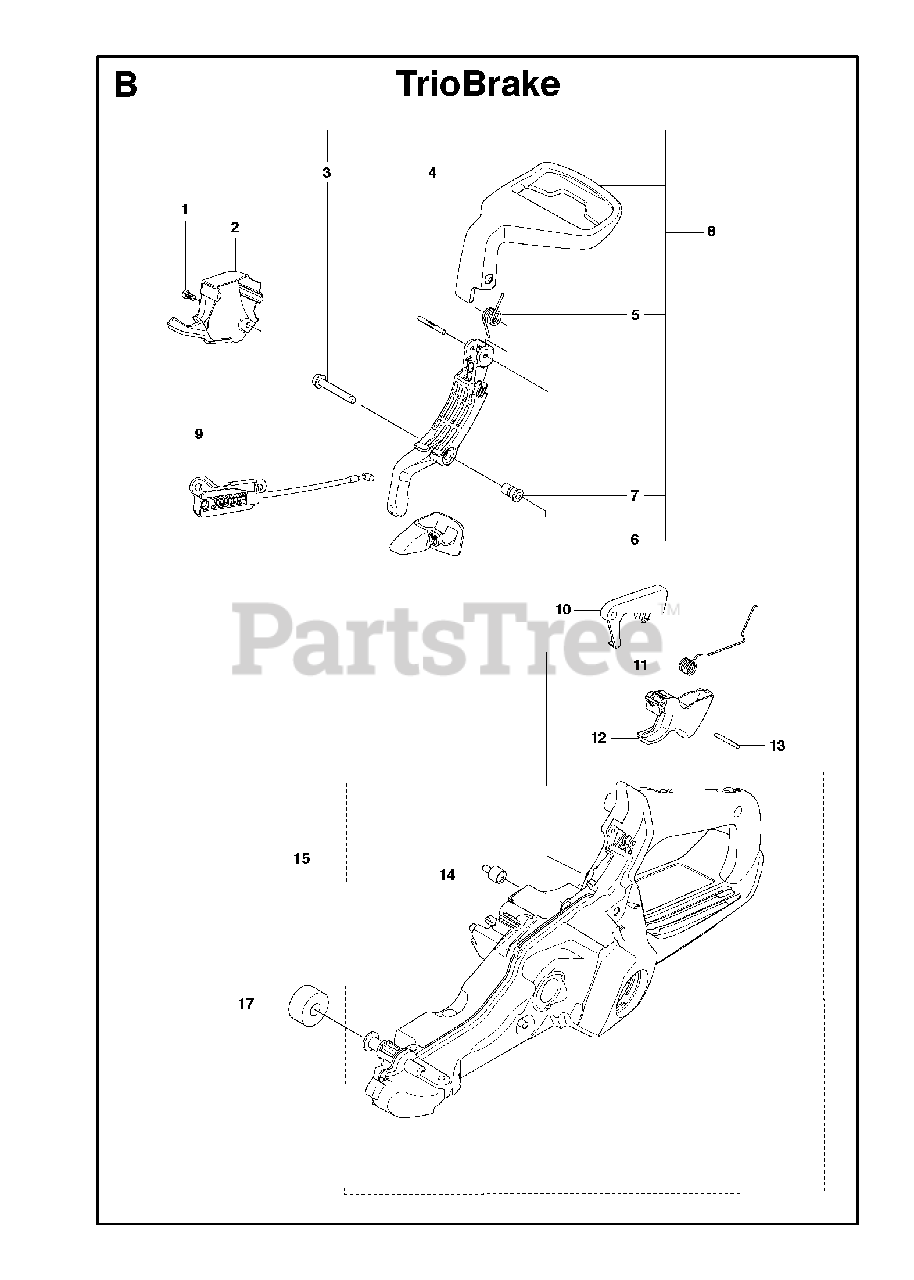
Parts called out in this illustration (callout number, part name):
3	Screw
4	Grooved Pin
5	Spring
6	BELLOWS
7	SLEEVE
8	HAND GUARD ASSY
10	THROTTLE LOCKOUT
14	FUEL TANK VENT
15	FUEL TANK ASSY
17	DEFLECTION LIMITER
